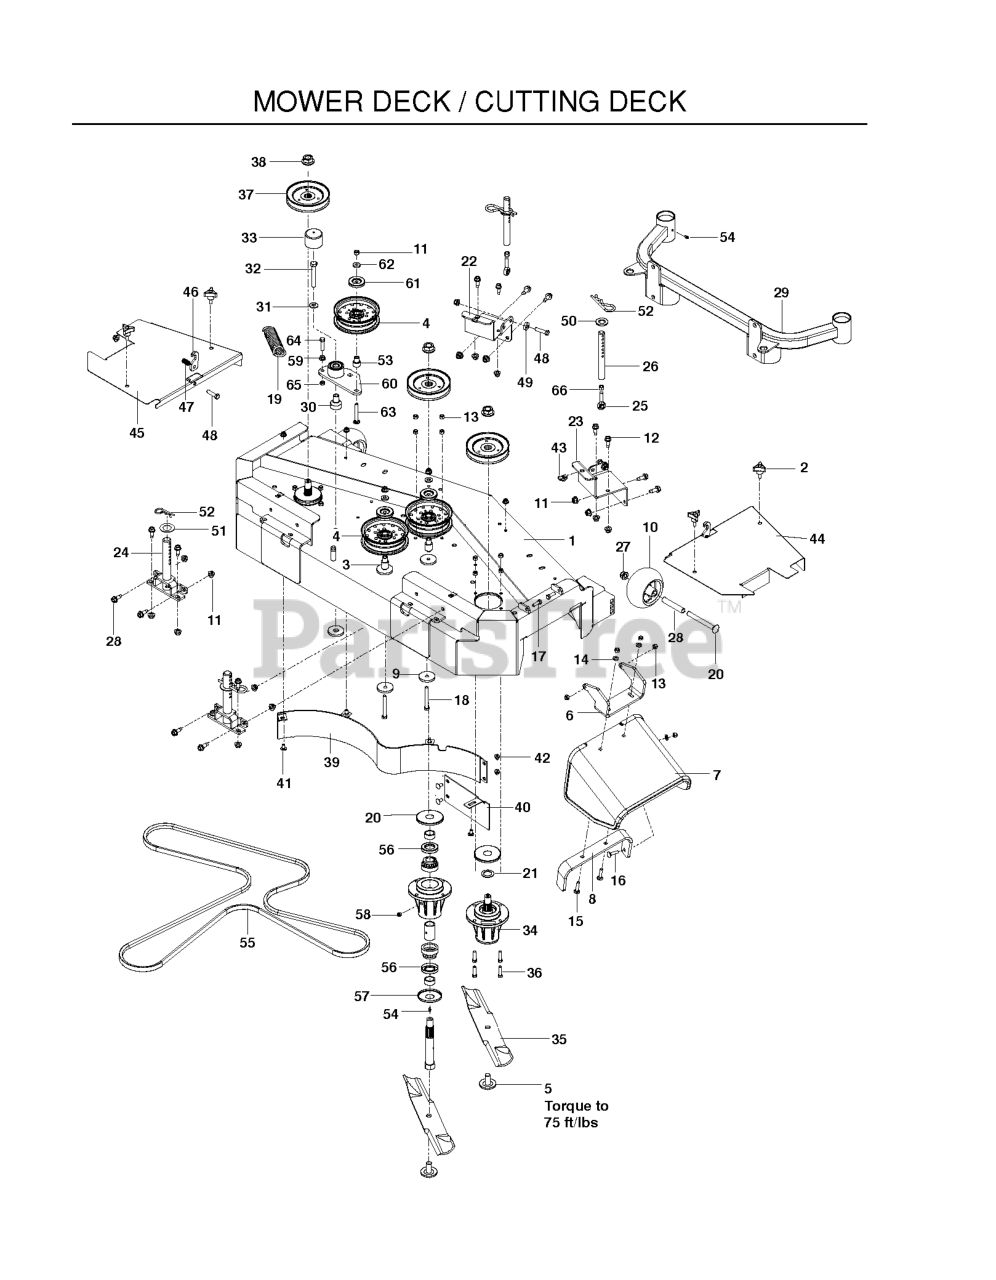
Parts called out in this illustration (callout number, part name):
1	CUTTER DECK 48" W/DECALS
2	KNOB W/STUD
3	IDLER BUSHING
4	IDLER PULLEY
5	BLADE BOLT/WASHER
6	HINGE CHUTE - BLACK
7	CHUTE, RUBBER DISCHARGE WB
8	BRKT, REINF-CHUTE WB
9	SPINDLE WASHER
10	ROLLER, GAUGE .635 BORN
11	NUT 3/8-16 HEX FLG NYLOC ZD
12	BOLT 3/8-16 X 1.0
13	NUT 5/16 NYLOC
14	FLAT WASHER 5/16 SAE
15	RHSNB 5/16-18 X 1-1/2 GR 5 ZD
16	BOLT, CARRIAGE 5/16X1-1/4
17	HCS 5/16C X 1
18	HCS 3/8C X 3
20	RHSNB 1/2-13 X 4.75 GR5 ZD
21	MACHINE BUSHING
22	SUPPORT - FRONT, LH
23	SUPPORT - FRONT, RH ORANGE
25	ROD END - 3/8-24 RH
27	NUT, 1/2-13 HEX FLG NYLOC ZD
28	TUBE, ROLLER AXLE
29	SUPPORT, CASTER 48 OR
30	PIVOT, BEARING
31	CONTACT BELLSPR 1/2
32	HCS 1/2C X 3 1/4
33	CAP, VINYL
34	HOUSING ASM, 72
35	BLADE OEM 16 1/4"
36	HCS 5/16C X 1 1/4
37	PULLEY - 5.25
38	NUT FLANGE 3/4-16
39	BAFFLE WLDT, BLACK
40	CENTER BAFFLE 48"
41	CARRIAGE BOLT 5/16C X 5/8"
42	5/16-18 NYLOC FLANGE NUT
43	U-CLIP 5/16-18 NUT RETAINER
44	COVER, 48 RH GY
45	COVER, 48 LH GY
47	SPRING - COMPRESSION
48	HCS 3/8C X 1 1/2
49	WASHER 3/8 X 3/4 X .187 TK
50	WASHER 3/4 FLAT SAE ZD
53	BUSHING, IDLER
55	BELT, 134.5
56	SHAFT SEAL
57	BOTTOM DUST CAP
58	PLUG-VENTED
59	NUT 3/8C WHIZ
60	ARM-IDLER W/BRG
61	DUST SHIELD
62	WASHER, 3/8 THICK
63	RHSNB 3/8-16 X 2.75
64	HCS 3/8-16 X 1-1/2
65	NUT 3/8-16 HEX JAM
